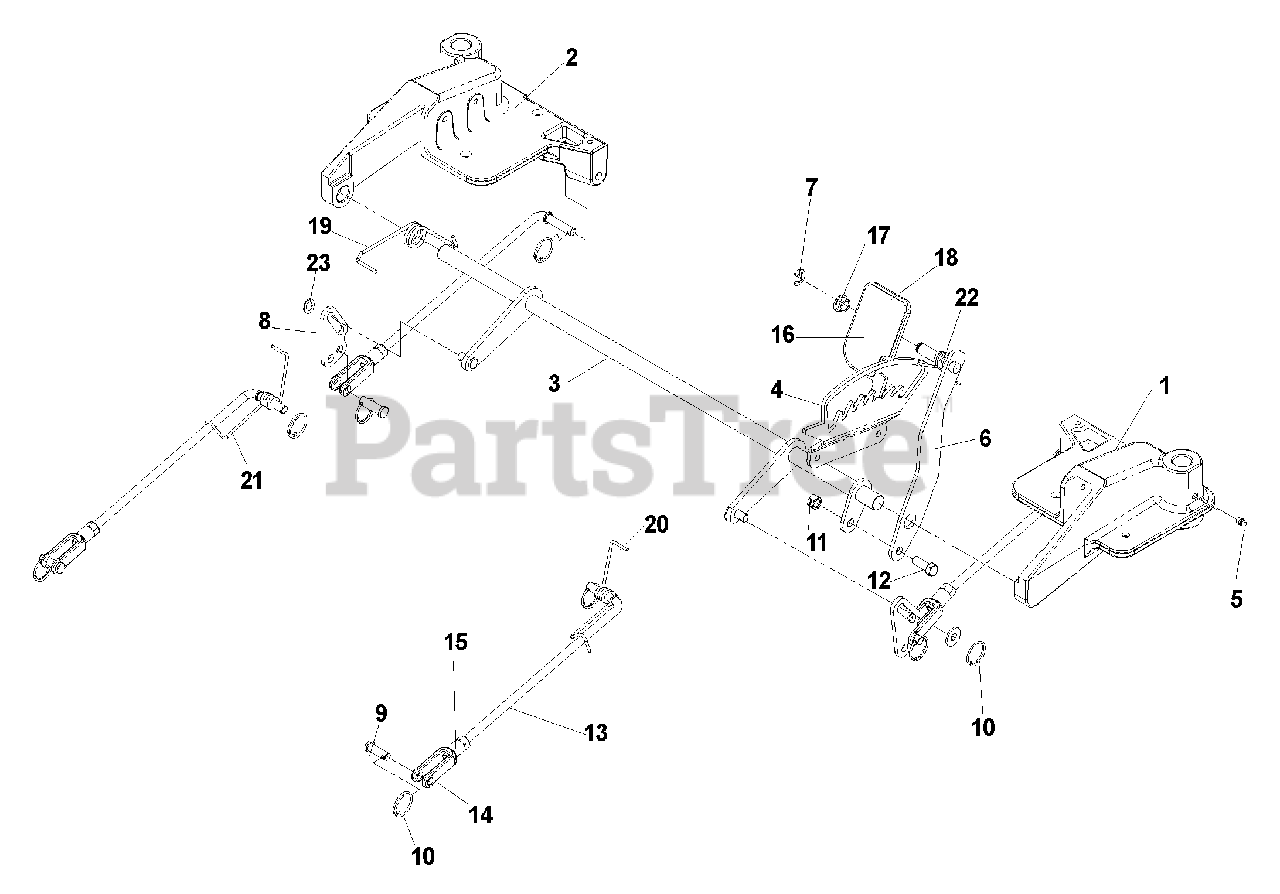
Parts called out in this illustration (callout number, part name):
1	STEERING CASTER, RIGHT
2	STEERING CASTER, LEFT
3	DECK LIFTER
4	DECK HEIGHT ADJUSTOR
6	FOOTLEVER
7	E-RING, 1/2"
8	DECK LIFT CONNECTOR
9	CLEVIS PIN
10	RETAINER, RING
11	NUT, 3/8C, CENTER LOCK
12	HCS 3/8-16 X 1, GR8
14	YOKE, 3/8F
16	FOOT PAD, NON-SLIP
17	BUSHING, NYLON FLANGED
18	FOOT PEDAL
19	TORSION SPRING, DECK LIFT
20	SPRING, DECK ROD, RIGHT
21	SPRING, DECK ROD, LEFT
22	SPRING, PEDAL, LIFT
23	WASHER, 5/16
